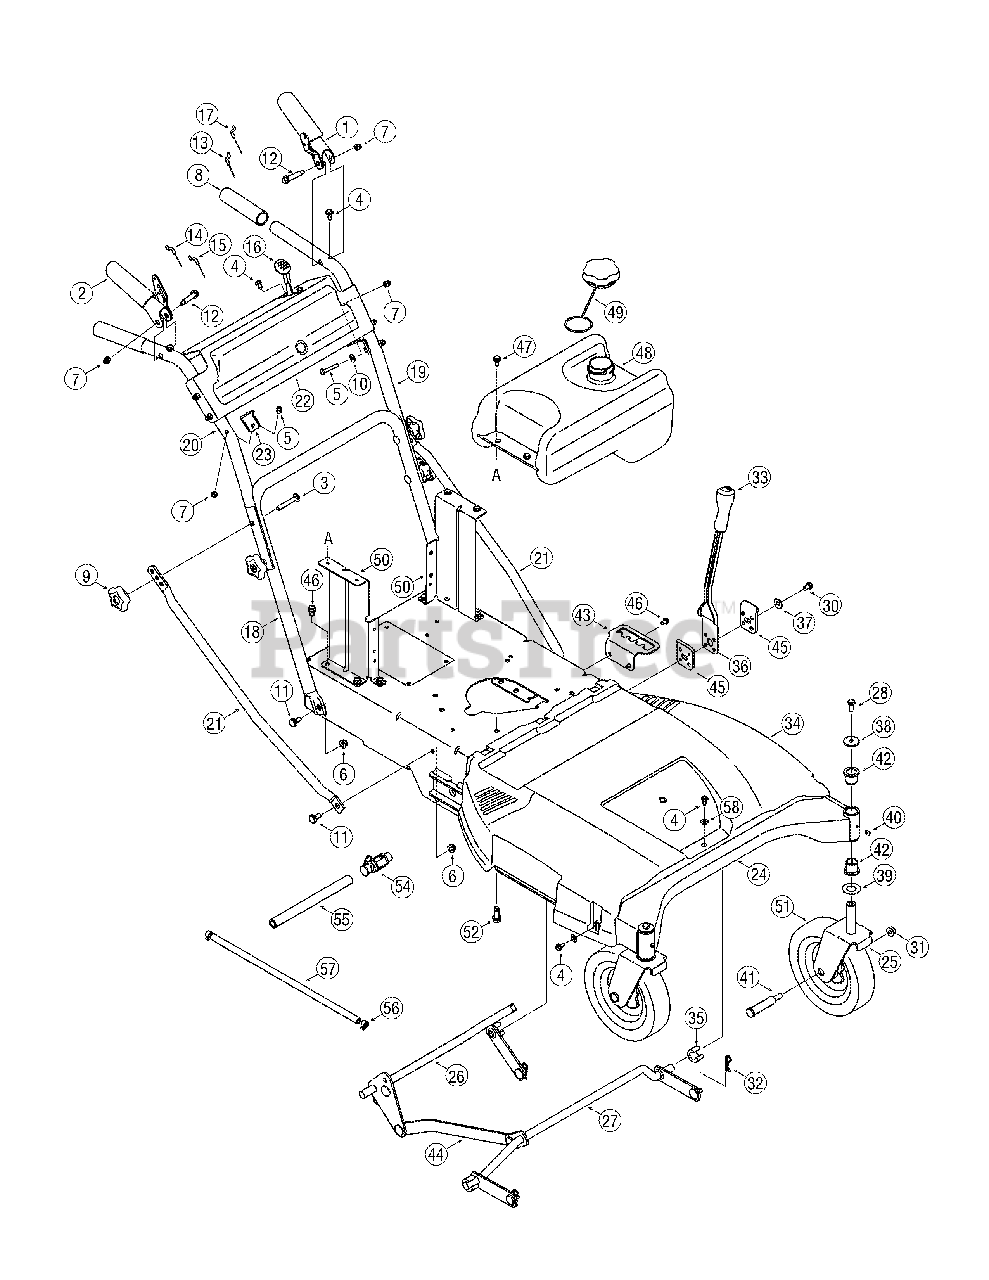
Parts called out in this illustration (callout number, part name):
1	Lever Assembly: LH
2	Lever Assembly: RH
3	Screw, Carriage: 5/16-18 x 2.25"
4	Screw, TT: 1/4-20 x 0.500"
5	Screw, HH Cap: 1/4-20 x 1.50"
6	Nut, Flange Lock: 5/16-18
7	Nut, Lock Cap: 1/4-20
8	Grip: 1.0" ID x 5.0" Lg
9	Star Knob 5/16-18
10	Washer, Flat: .25 x .63 x .0515
11	Screw, Shoulder: .435" x .178-5/16
12	Screw, Shoulder: .375" x 1.355" x 1/4-20
13	Cable, Clutch Wheel
14	Cable, Brake, Transmission: RH
15	Cable, Clutch Deck
16	Cable, Throttle/Choke: 38" x 1.1" Ext
17	Cable, Brake, Transmission: LH
28	Screw, HH Cap: 5/16-24 x .750"
30	Screw, HH Cap: 5/16-18 x .50"
31	Nut, Flange Lock: 3/8-16
32	Click Pin: .092" x 1.64"
33	Handle Grip 1/2"
34	Belt Cover 33" Wide Cut Mower
35	Snap Spacer: .63" ID x .75" LG
36	Deck Height Lever
37	Washer, Bell: .340" x .872" x .060"
38	Washer, Flat: .330" x 1.25" x .120"
39	Washer, Flat: .760" ID x 1.50" OD
40	Lube Fitting: 3/16: LNC #70
41	Bolt, Shoulder: .625" x 2.515" x 3/8-16
42	Flange Bearing: .760" x .941" x 1.0"
46	Screw, TT: 5/16-18 x .625"
47	Screw, Shoulder: .3175" x .188" x 1/4-20
48	Fuel Tank, 2 Gal.
49	Fuel Cap
51	Wheel, 8" x 1.75"
52	Screw, TT: 3/8-16 x 1.25"
54	Oil Drain
55	Oil Drain Hose
56	Hose Clamp
57	Fuel Hose
